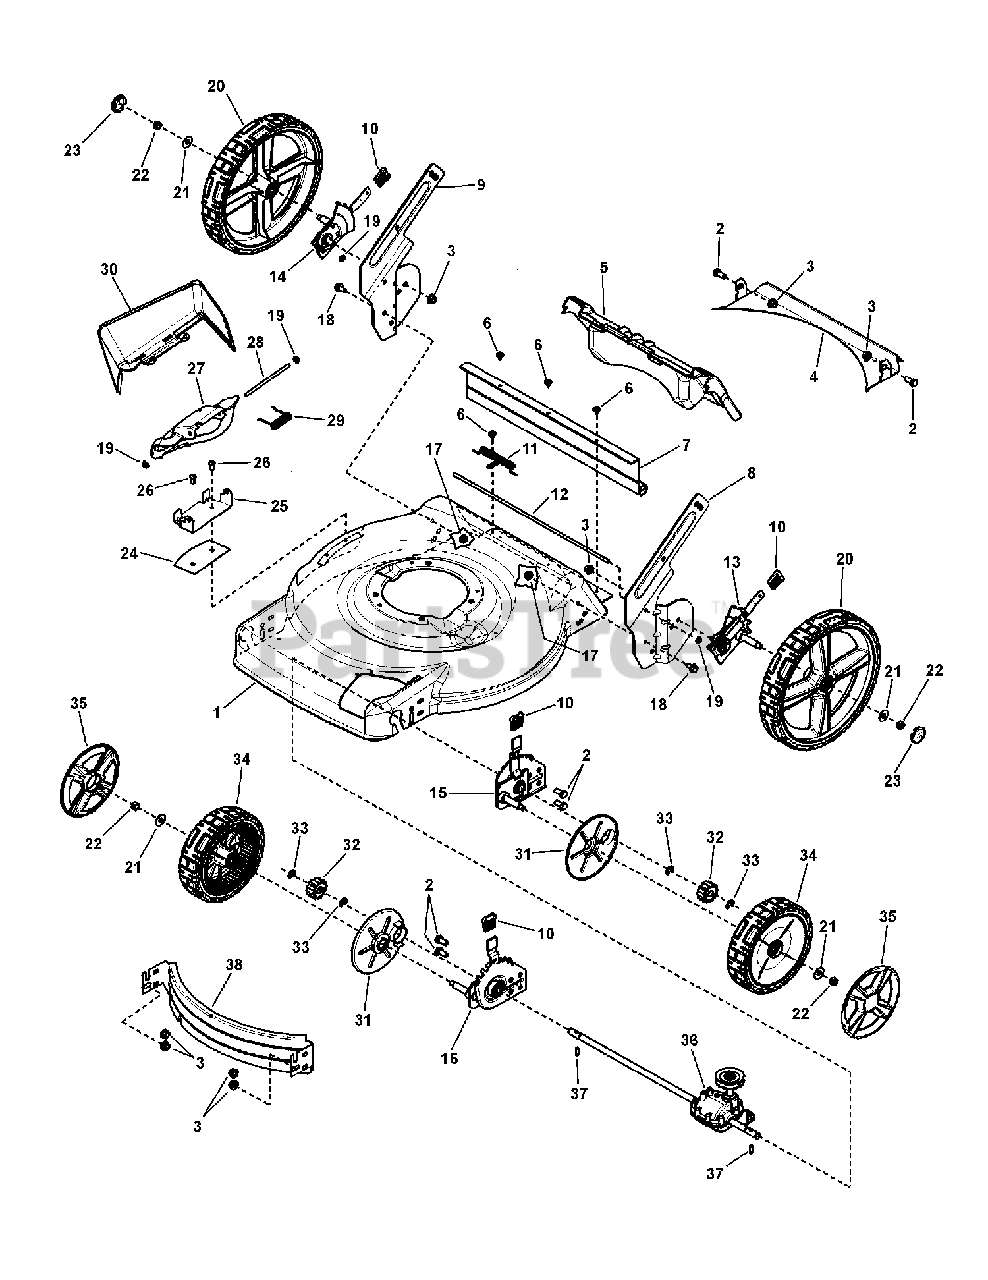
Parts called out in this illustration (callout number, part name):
1	DECK, 22 Walk, 3-N-1
2	SCREW, 3/8-16 x 3/4" Hex Head Cap, GR 5, YZ
3	NUT, 3/8-16 Hex Flange Lock, YZ
4	BAFFLE, Rear, 22 Deck
5	DOOR, 22" Rear
6	SCREW, #10-24 x 1/2 Hex Washer Self-Tap, SEMS
7	GUARD, Rear
8	BRACKET, Lower Handle, LH, 22" WBM, HW
9	BRACKET, Lower Handle, RH, 22" WBM, HW
10	GRIP, Height Latch - Black (1.3" Wide)
11	SPRING, Torsion, Rear Door, 22" WBM
12	ROD, Pivot, Rear Door (1/4" Dia. X 17-1/2")
13	ASSEMBLY, Height-Of-Cut, Left Rear, 22" WBM
14	ASSEMBLY, Height-Of-Cut, Right Rear, 22" WBM
15	ASSEMBLY, Height-Of-Cut, Left Front, 22" WBM, Propelled
16	ASSEMBLY, Height-Of-Cut, Right Front, 22" WBM, Propelled
17	NUT, 5/16-18 Flange Lock, YZ
18	BOLT, 5/16-18 x 5/8" Hex Flange Lock, YZ
19	PUSHNUT, 1/4"
20	* ASSEMBLY, Wheel, 12 x 2 Idle, BB, Snapper Cool Gray
21	WASHER, 1" O.D. x .387 I. D. Flat
22	NUT, 3/8-16 Hex Center Lock, YZ
23	HUBCAP, 12 Wheel, Snapper Cool Gray
24	PLATE, Mulch, 22" RB Scott's
25	BRACKET, Chute
26	SCREW, 1/4-20 x 11/16 Pan Head Torx, Self-Tap
27	COVER, Mulch, Plastic, Black
28	ROD, Pivot (1/4" Dia. x 5.55")
29	SPRING, Torsion, Chute
30	SIDE CHUTE, Plastic, Black
31	DUST SHIELD, 22" WBM, Front Wheel Drive
32	GEAR, Pinion, 22" WBM, Front Wheel Drive
33	RING, External Retaining
34	* ASSEMBLY, Drive Wheel, 8 x 2, BB, Snapper Charcoal Gray
35	HUBCAP, 8 & 9 Wheel Spoked - Snapper Cool Gray
36	TRANSMISSION, Rocker, 22 WBM HW, VS
37	DRIVE PIN, 22" WBM, Front Wheel Drive
38	BAFFLE, Front, 22 WBM
